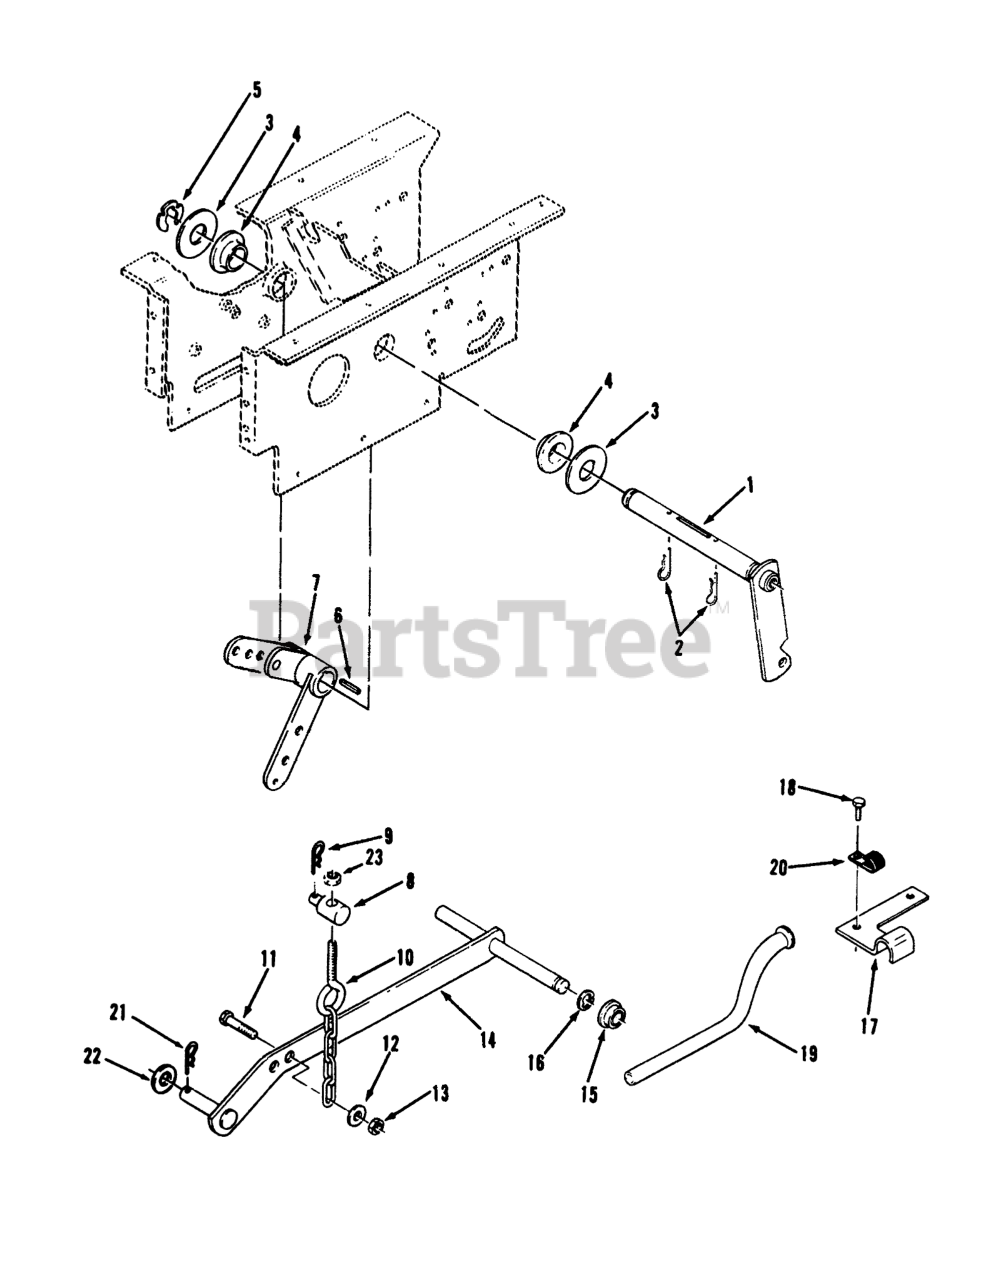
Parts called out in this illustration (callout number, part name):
1	WLDMT-LIFT ARM
2	Pin-Cotter
3	WASHER-FLAT
4	BEARING-FLANGE
5	PIN-SPRING
6	KEY-SQUARE
7	LIFT LEVER ASM
8	TRUNNION
9	Hairpin Cotter
10	CHAIN-LIFT
11	SCREW-HH
12	WASHER-PLAIN
13	NUT-LOCK, NI
14	Bar-Lift
15	BUSHING
16	RING-RETAINING, EXTERNAL
17	CLAMP-CONDUIT R
18	SCREW-HH, LOCK
19	TUBE-CONDUIT R
20	CLIP
21	Hairpin Cotter
22	WASHER-FLAT
23	NUT-LOCK, NI
